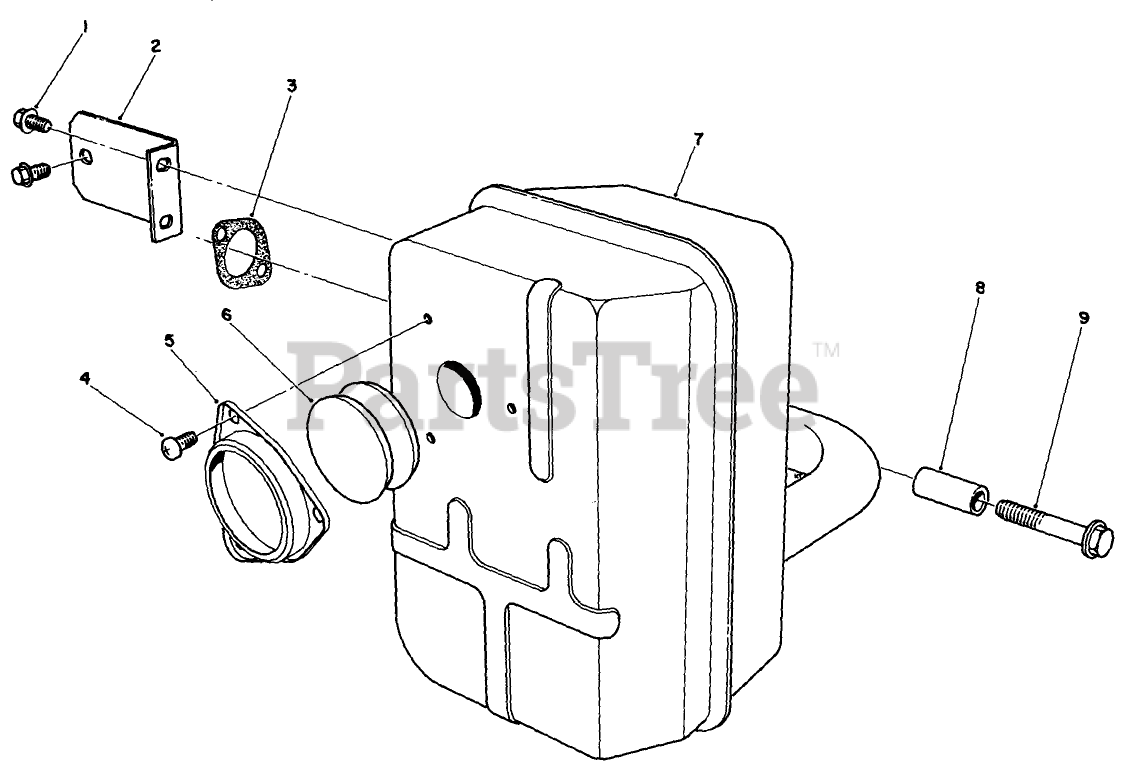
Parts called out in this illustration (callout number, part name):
1	Bolt-Flanged (8X12)
6	Arrester-Spark
7	Muffler Assembly
9	Bolt-Flanged (8X45)
